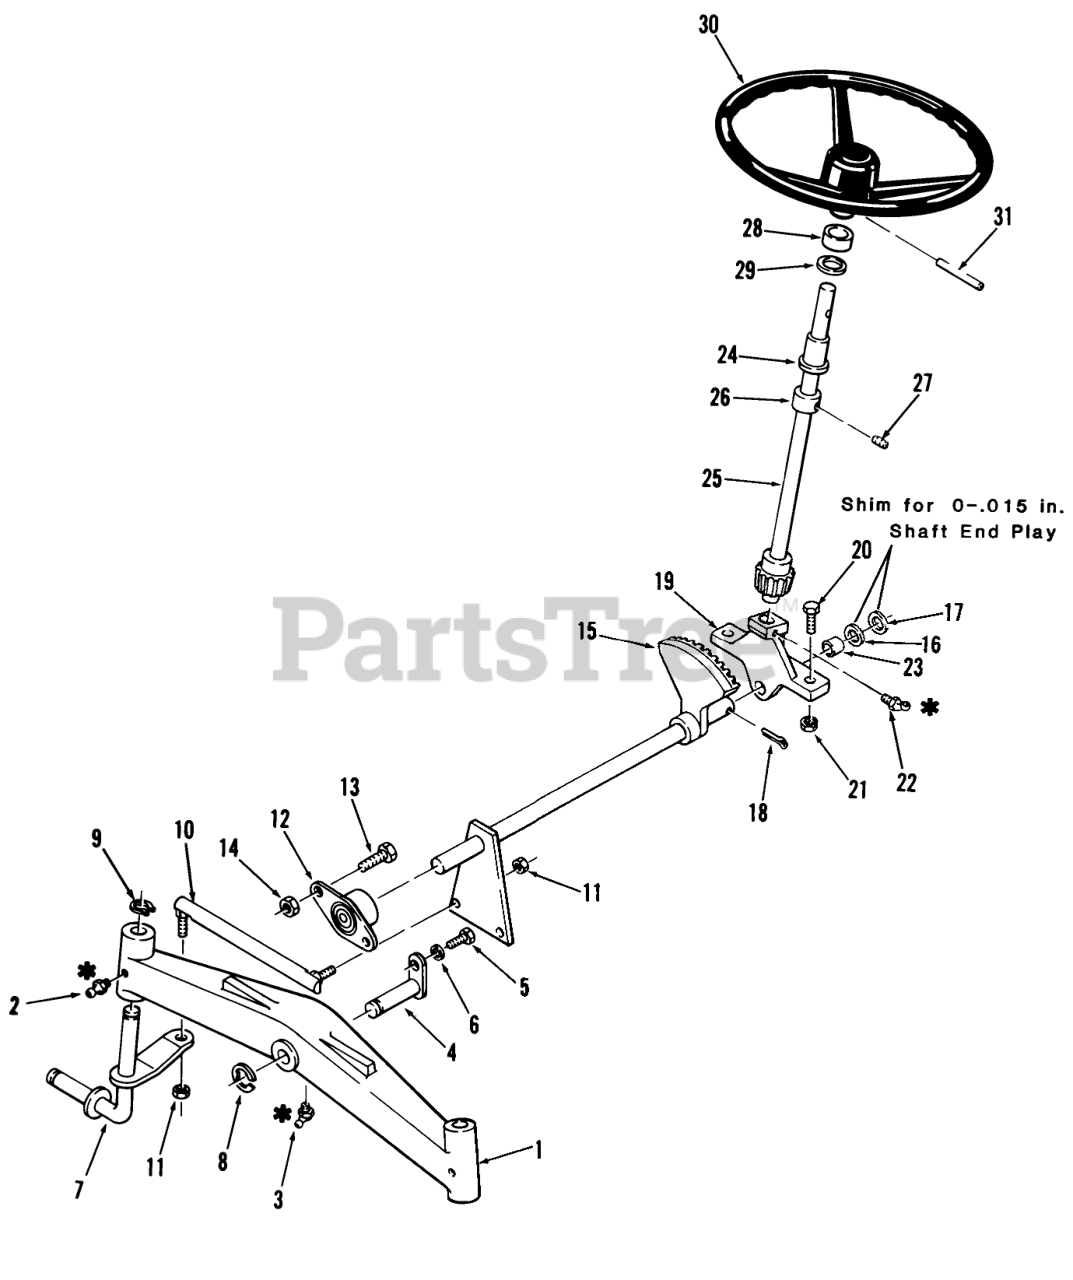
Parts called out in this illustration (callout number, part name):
1	AXLE-FRONT
2	Zerk
3	FITTING-GREASE
4	PIN AND PLATE ASM
5	H H C S
6	Lockwasher
7	Front Spindle RH
7	Front Spindle LH
8	E-RING
9	Snap Ring
10	Tie Rod RH
10	Tie Rod LH
11	NUT-6
12	BEARING-FLANGED
13	Bolt
14	Nut
15	Assy-Steering
16	WASHER-SHIM
17	WASHER
18	PIN-4
19	Support
20	BOLT
21	Nut
22	FITTING-GREASE
23	BEARING-BRONZE
24	BEARING
25	Shaft-Upper Steering
26	Collar
27	SCREW-SET
28	Collar
29	WASHER-BOWED
30	STEERING WH 13" PLAS
31	Pin-Roll
